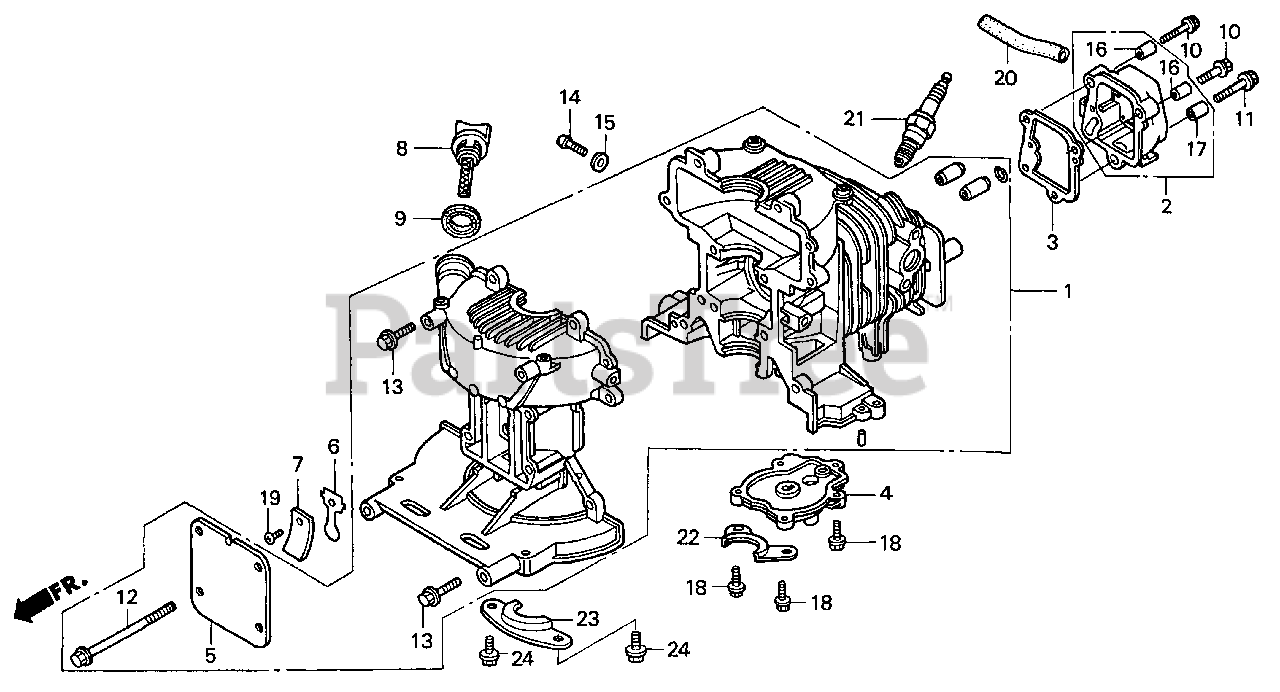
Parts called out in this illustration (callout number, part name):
1	CRANKCASE SET
2	COVER COMP., HEAD
3	GASKET, HEAD COVER
4	COVER, CAMSHAFT
5	COVER, OIL OUTLET VALVE
6	VALVE, OIL OUTLET
7	PLATE, STOPPER
8	CAP, OIL FILLER
9	GASKET, OIL FILLER CAP
10	BOLT, FLANGE (5X22)
11	BOLT, FLANGE (5X14)
12	BOLT, FLANGE (5X55)
13	BOLT, FLANGE (5X18)
14	SCREW, PAN (6X8)
15	WASHER, SEALING (6.5MM)
16	COLLAR, HEAD COVER
17	COLLAR A, HEAD COVER
18	BOLT-WASHER (4X16)
19	SCREW, PAN (3X5)
20	BULK HOSE, VACUUM (7X3000) (7X68)
21	SPARK PLUG (U16FSR-UB)
21	SPARK PLUG (R5HSB)
22	GUARD A, GRASS
23	GUARD B, GRASS
24	BOLT-WASHER (4X10)
